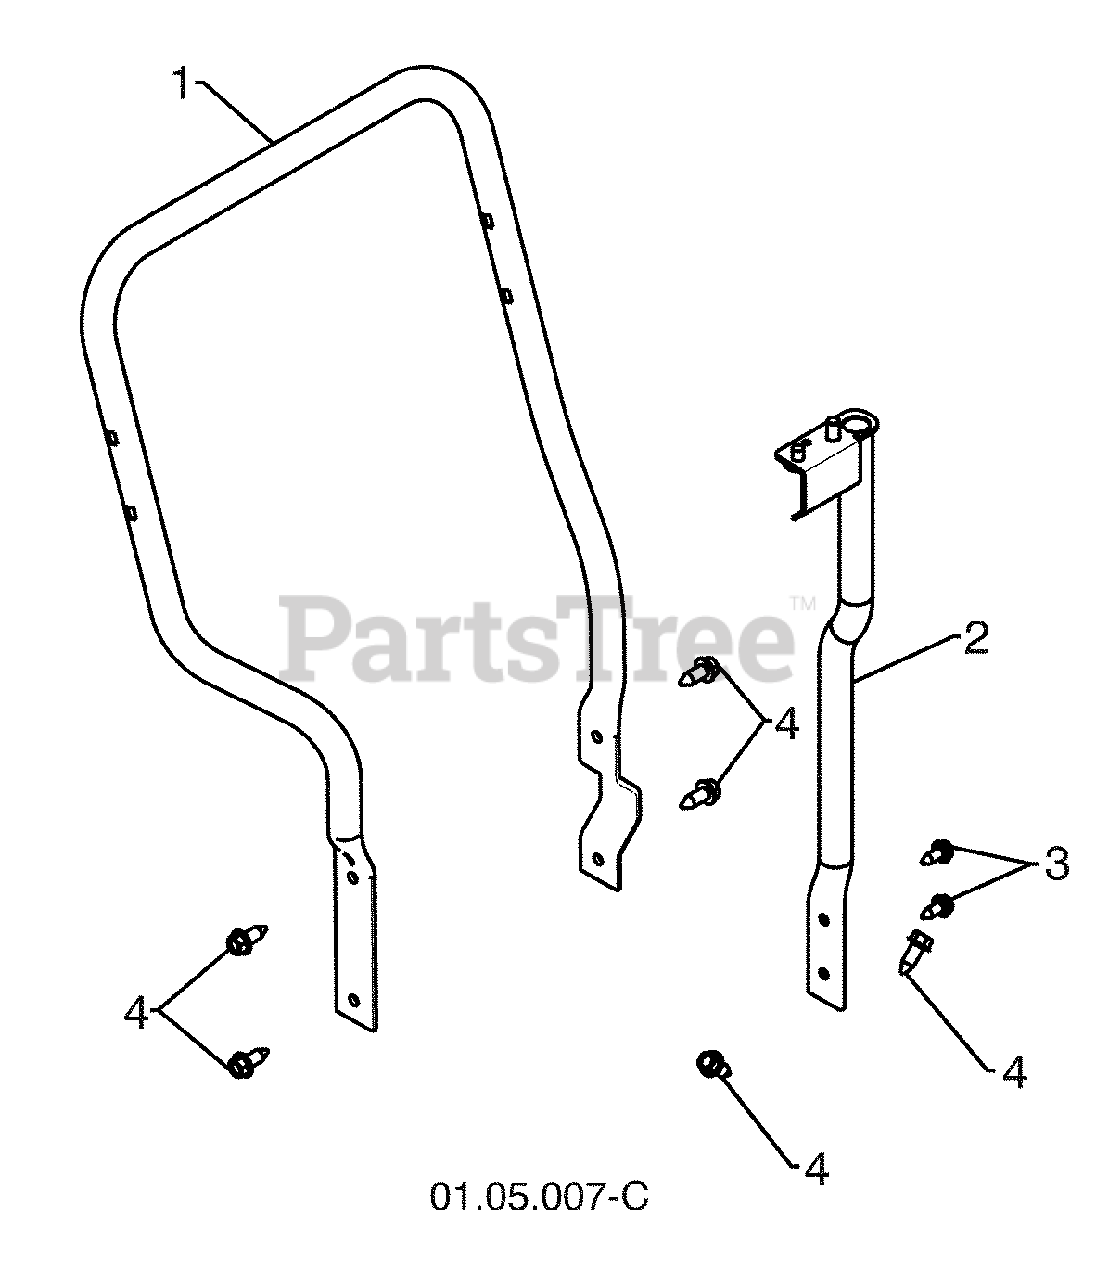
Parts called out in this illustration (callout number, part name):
1	LOWER TUBE GRAY
2	PIVOT SUPPORT
3	BOLT 5/16-18 X .750
4	SCREW 3/8-16 X 1.00
